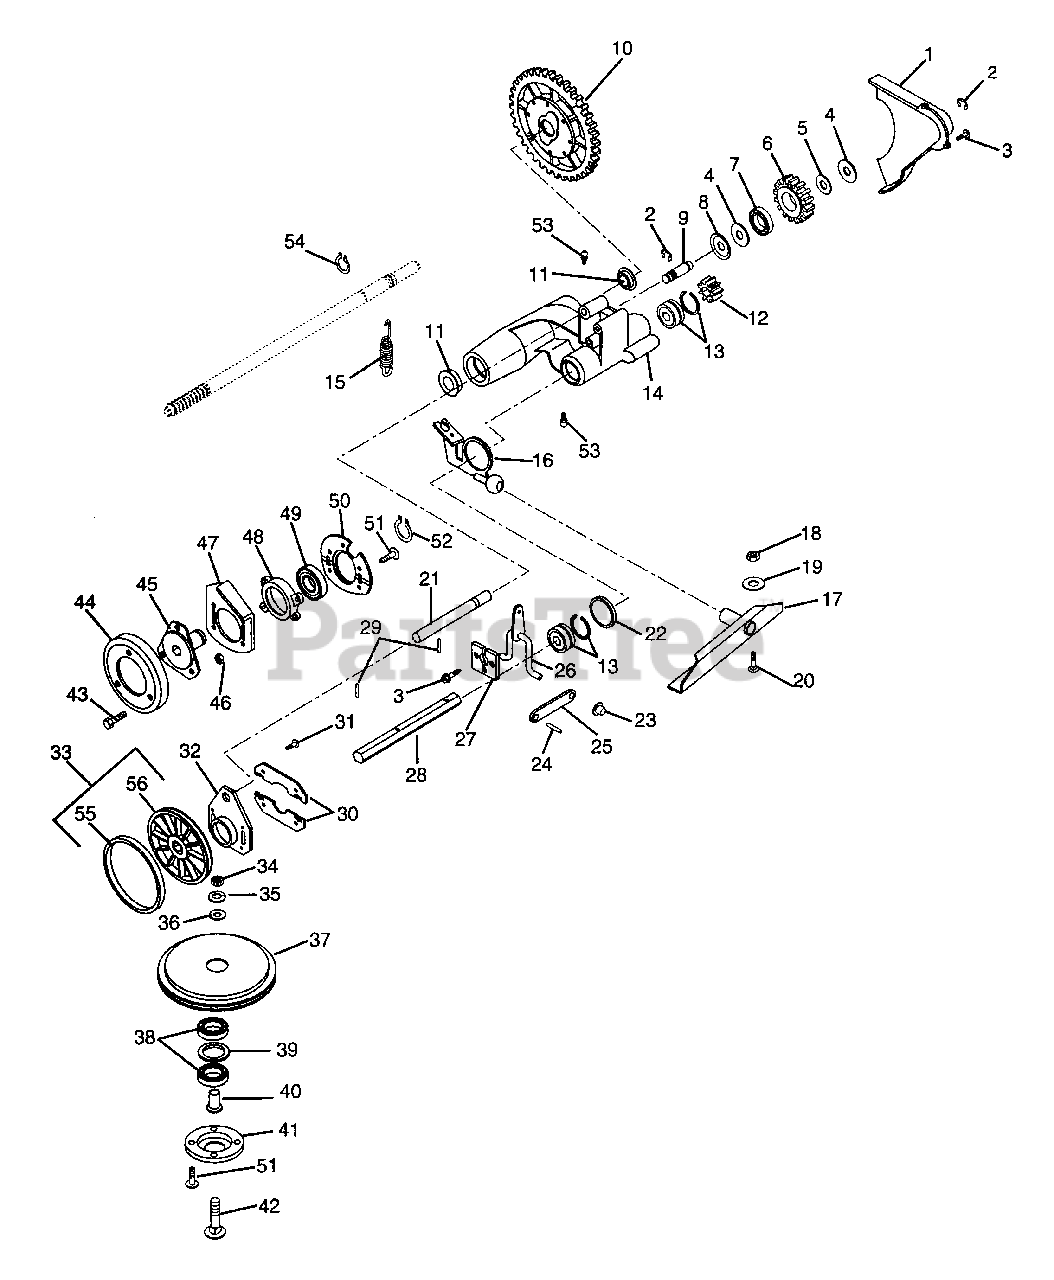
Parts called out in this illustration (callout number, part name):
1	GEAR COVER
2	RG-RTNG-EXT .438X.035
3	@SCR-TAP 12-24X.50 HWH TR YWZC
4	WSHR-FL-STL .520X.827X.062 YZ
5	@WSHR-FL-STL.531X1.06X.095YWZC
6	IDLER GEAR
7	BRG-BALL .500X1.38X.437
8	RETAINER
9	IDLER SHAFT
10	DIFFERENTIAL ASSEMBLY
11	BRG-BALL .625X1.383X.50
12	PINION
13	BRG-BALL .562X1.375X.437
14	DRIVE MOUNT
15	SG-TENS .051X.60X2.25 WLD 7.0
16	DRIVE ACTUATOR WELDMENT
17	PIVOT CHANNEL WELDMENT
18	@NUT-LK-CTR .31-18 YWZC
19	@WSHR-FL-STL.344X.688X.065YWZC
20	@BLT-RHDSSQNK .31-18X.62 G5YZ
21	ROD - GUIDE
22	WSHR-FL-STL 1.390X2.00X.020 PL
23	PUSH NUT, .25
24	PIN-ROLL .125X.50
24	PIN-ROLL .125X.63
25	SHIFT LINK
26	SHIFT ARM WELDMENT
27	RETAINER PLATE
28	HEX SHAFT
29	PIN-ROLL .188X.88
30	THRUST PLATE
31	@SCR-TAP 10-24X.375 HWH YZ TR
32	GUIDE PLATE
33	FRICTION WHEEL ASSEMBLY
34	@NUT-HEX .31-18 YWZC
35	@WSHR-LK .31X.078 REG YWZC
36	WSHR-FL-STL .328X.875X.062YWZC
37	FRICTION SHEAVE
38	BRG-BALL .625X1.375X.44
39	WSHR-FL-STL 1.062X1.344X.032PL
40	SPINDLE - BEARING
41	RETAINER - BEARING
42	@BLT-RDHDSQNK .31-18X1.75 G5YZ
43	@BLT-HEX .25-20X.50 GR5 YWZC
44	FRICTION DISC
45	FRICTION WHEEL HUB
46	@NUT-LK-CTR .25-20 YWZC
47	BEARING PLATE
48	BEARING RETAINER
49	BRG-BALL 1.0X2.0X.56
50	BEARING RETAINER
51	@SCR-TAP 12-24X.50 HWH TR YWZC
52	RG-RTNG-EXT .875X.042
53	FTG-LUBE .25-28X.256 YWZC
54	RG-RTNG-EXT .625X.035
55	FRICTION RING
56	FRICTION WHEEL HUB
